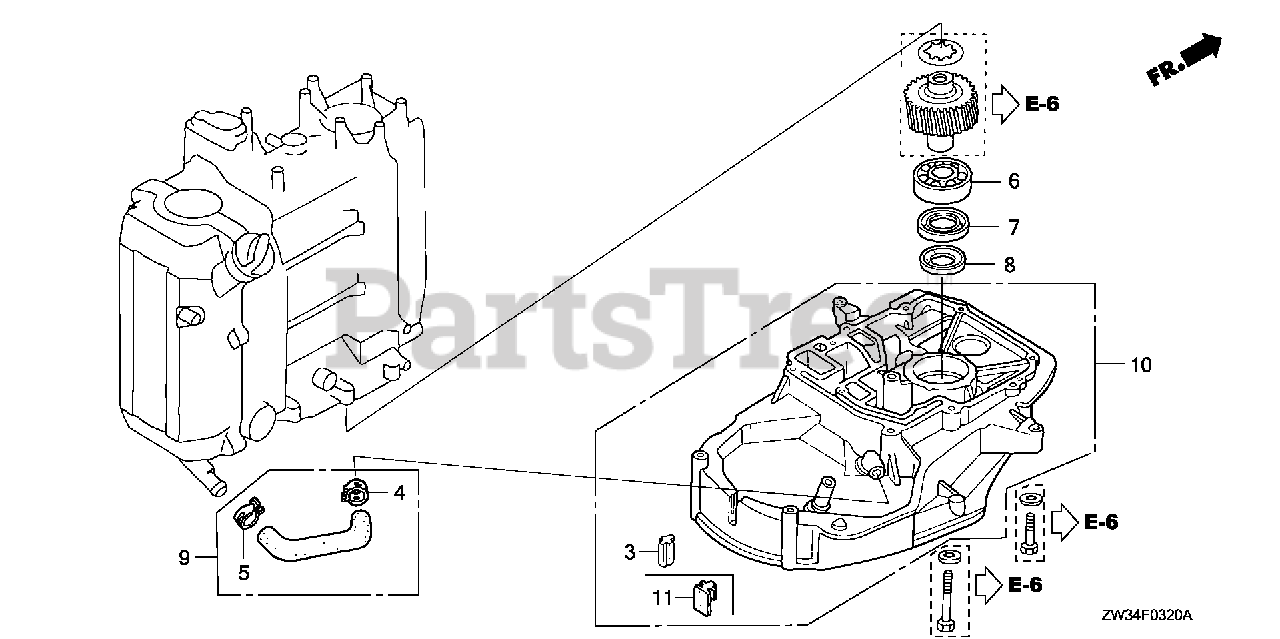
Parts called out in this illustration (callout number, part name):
1	TUBE, OIL
2	CASE KIT, PRIMARY GEAR *NH8* (DARK GRAY)
3	RUBBER, SEAL
4	CLAMP, TUBE (D18.8)
5	CLAMP, TUBE (D21)
6	BEARING, RADIAL BALL (6205)
7	OIL SEAL (25X40X7)
8	SEAL, WATER (17X26X7)
9	TUBE SET, OIL
10	CASE KIT, PRIMARY GEAR *NH8* (DARK GRAY)
11	RUBBER, MOUNT CASE SEAL
